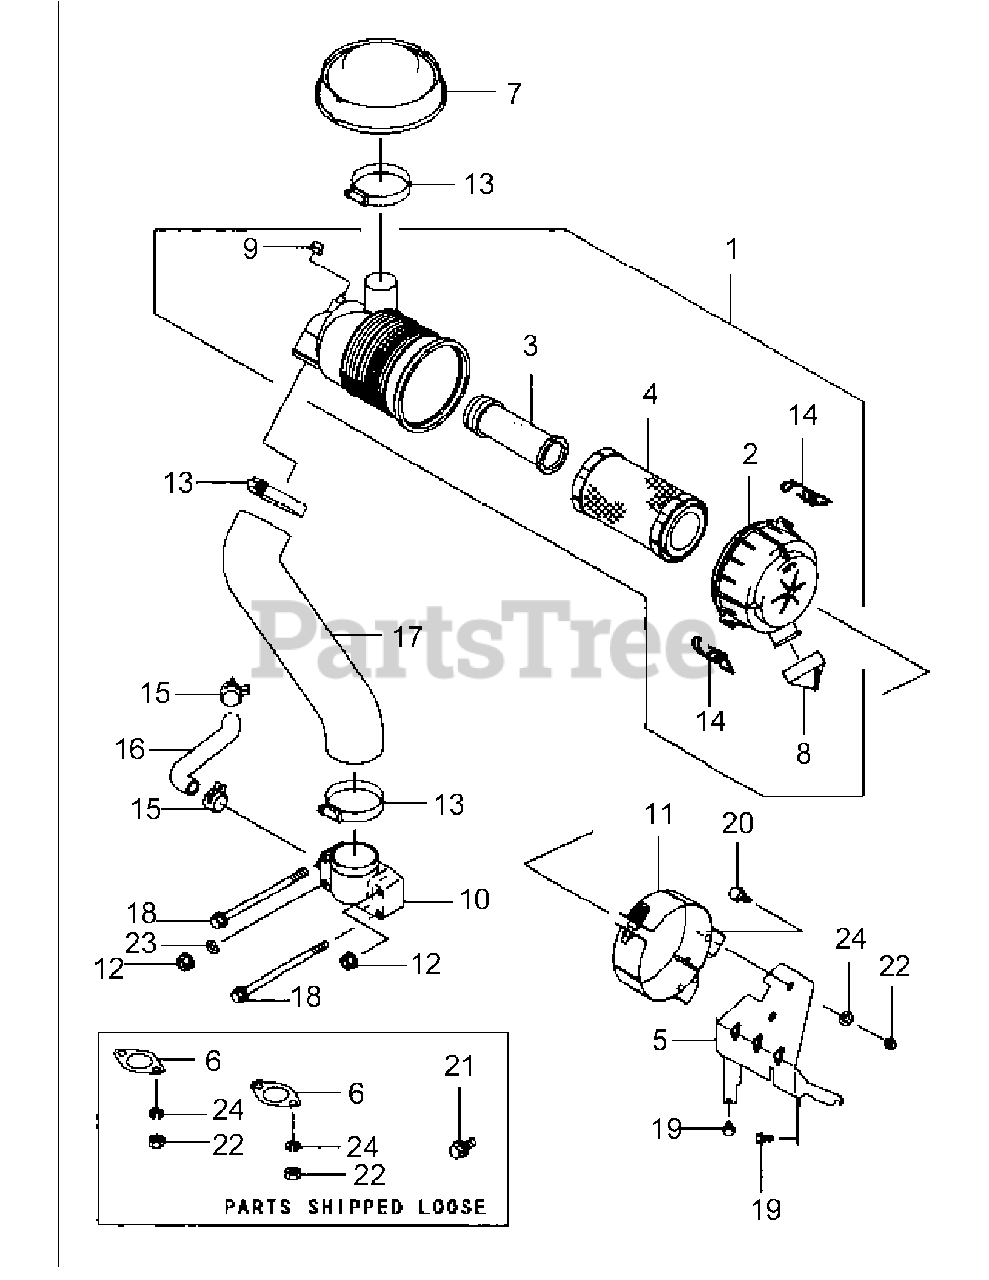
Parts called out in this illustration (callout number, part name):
1	AIR FILTER ASSY.
2	AIR FILTER CASE
3	SECONDARY FILTER ELEMENT
4	PRIMARY FILTER ELEMENT
6	MUFFLER GASKET
7	CAP
10	INTAKE PIPE
13	CLAMP
15	CLAMP
17	TUBE
19	FLANGED BOLT
20	FLANGED BOLT
21	FLANGED BOLT
22	SMALL HEX NUT
23	PLAIN WASHER
24	SPRING WASHER
